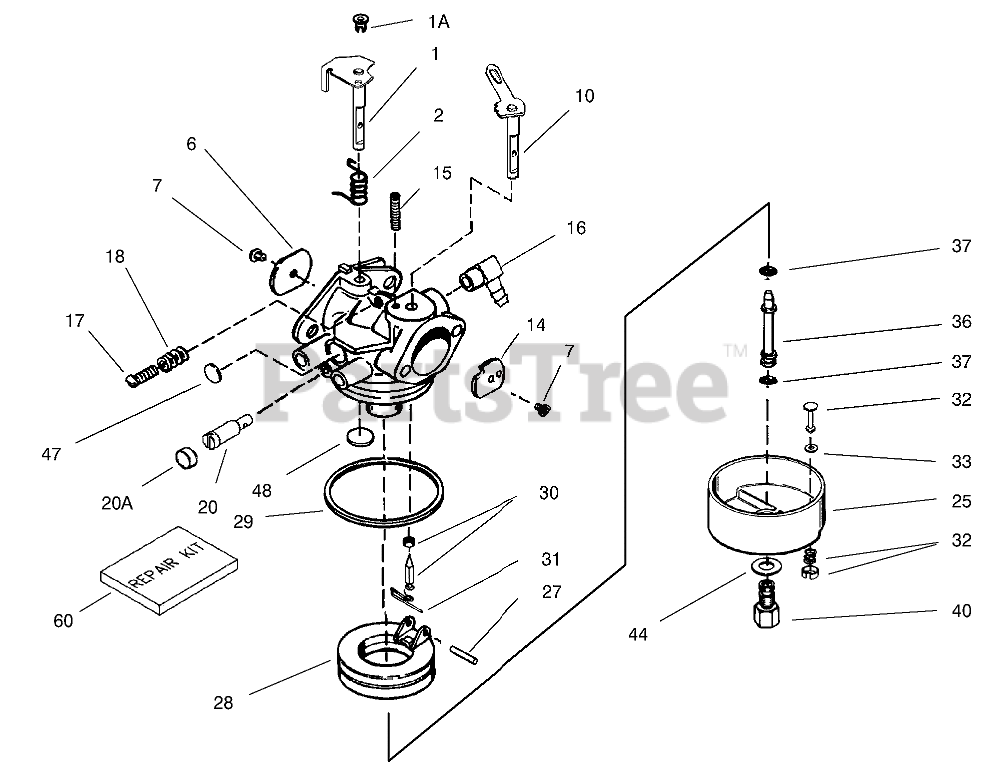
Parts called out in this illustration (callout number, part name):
1	Throttle Shaft and Lever ASM
1A	Bushing
2	Spring-Return, Throttle
6	Shutter-Throttle
7	Screw-Shutter
10	Choke Shaft and Lever ASM
14	Shutter-Choke
15	Spring-Positioning, Choke
16	Fitting-Fuel
17	Screw-Throttle Crack and Idle Speed
18	Spring-Tension
20	Screw-Restrictor, Idle
20A	Cap-Screw, Idle Restrictor
25	Float Bowl ASM (Incl. Ref. #32 and 33)
27	Shaft-Float
28	Float
29	O Ring-Bowl, Float
30	Inlet Needle, Seat, Clip (Incl. Ref. #31)
31	Clip-Spring
32	Bowl Drain ASM
33	Gasket-Plunger, Drain
36	Tube-Nozzle, Main
37	O-Ring
40	Nut-Bowl, High Speed
44	Washer-Nut, Bowl
47	Plug-Welch, Idle Mixture Well
48	Plug-Welch, Atmospheric Vent
60	Repair Kit
